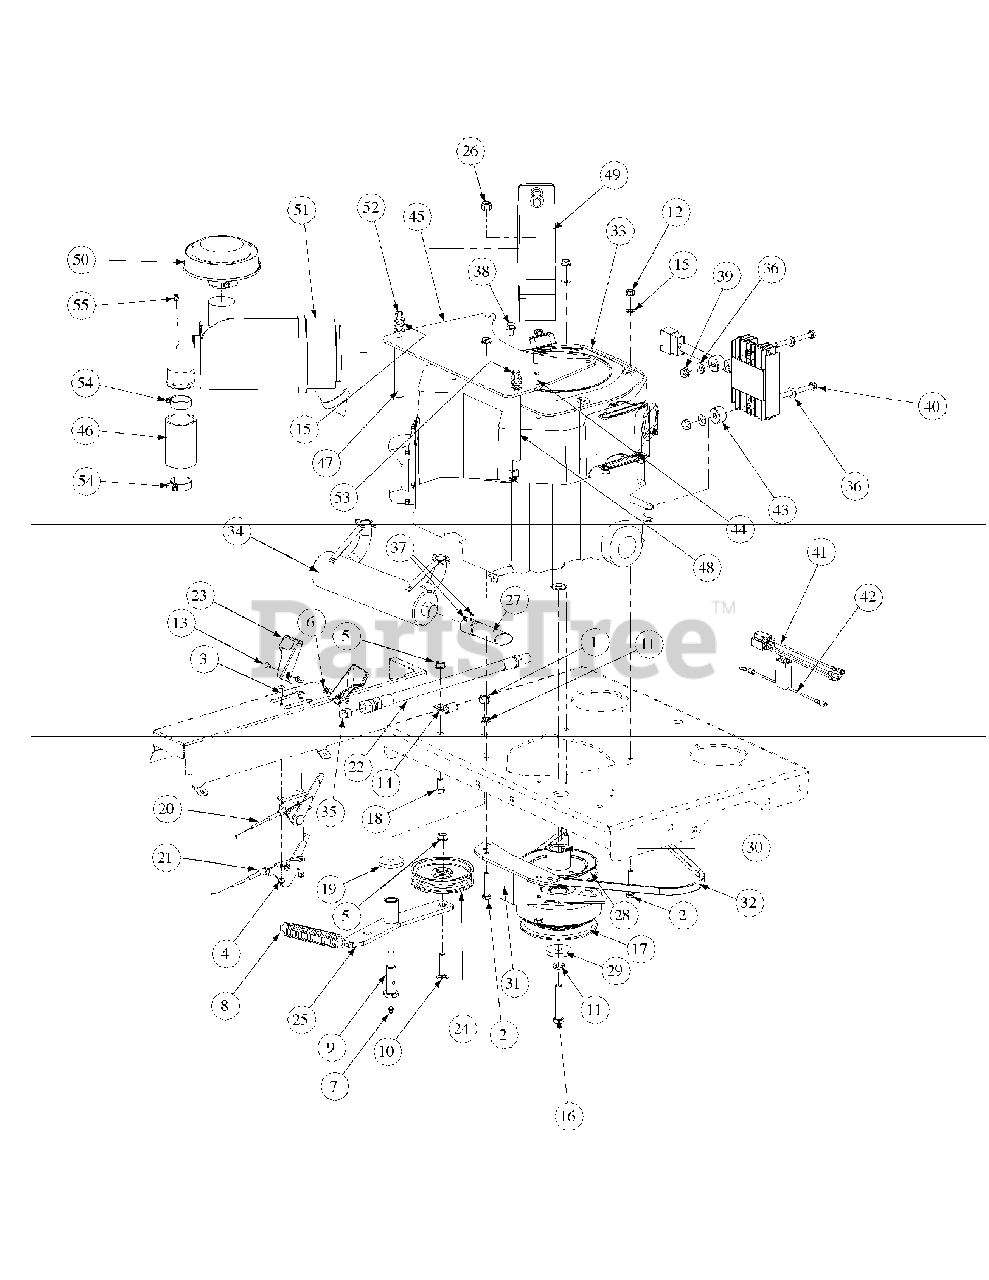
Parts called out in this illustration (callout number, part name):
1	Hex Nut, 7/16-14
2	HHCS, 5/16-18, 1-3/4
3	Round Hd. Machine Screw, 10-32 x 3/4
4	Lock Nut, Nylon Insert, 10-32
5	Flange Lock, Hex Nut, 3/8-16
6	Nut Washer, W/Star, 8-32
7	Grease Fitting, 1/4-28 x 3/16
8	Extension Spring, 1.0 OD x 5.125
9	Shoulder Screw, 7/16-14
10	Hex Carriage Screw, 3/8-16, 1.75
11	Lock Washer, 7/16
12	Hexflange Lock Nut, 5/16-18
13	Machine Screw, 8-32, .375
14	Clip, Heat Shield Cable
15	Flat Washer, 5/16
16	Capscrew, 7/16-20 x 2.50
17	Clutch Brake, 1.125 ID
18	Hex Cap Screw, 3/8-16, .750
19	Flat Washer, 7/16 ID x 1.75 OD x .25
20	Choke Control Cable
21	Throttle Control Cable
22	Oil Drain Hose
23	Control Throttle Knob
24	Flat Pulley with Flanges
25	Engine Idler Arm Assembly
26	Nut, 5/16-18, Nylock
27	Straight Exhaust Pipe
28	Pump Drive Pulley
29	Flat Washer, 7/16 ID x 1.75 OD x .25
30	Key, 1/4 x 1/4 x 3
31	Retainer Clutch Assembly, Ogura
32	Belt, 51.2 Lg
33	Engine, 24HP Honda
34	Muffler
35	Pipe Plug, 3/8 NPT
36	Flat Washer, 1/4
37	Screw, 8-32 x 0.375
38	Screw, M6 x 1.0 x 12mm
39	Nut, 1/4-20, Hex Flange Lock
40	Hex Cap Screw, 1/4-20 x 2.50
41	Wire Harness Adaptor
42	Charge Regulator Wire
43	Spacer, .281 ID x .875 OD
44	Hex Cap Screw, 5/16-18 x 3/4
45	Aircleaner Bracket
46	Hose, 2.00 ID x .19 wall
47	Spacer, .370 ID x .500 OD x 3.45
48	Spacer, .370 ID x .500 OD x 4.08
49	Aircleaner Band
50	Aircleaner Hood
51	Engine Aircleaner
52	Bolt, 6MM x 120MM
53	Bolt, 6MM x 130MM
54	Hose Clamp
55	Nylon Pipe Plug, 1/8-27 NPT
